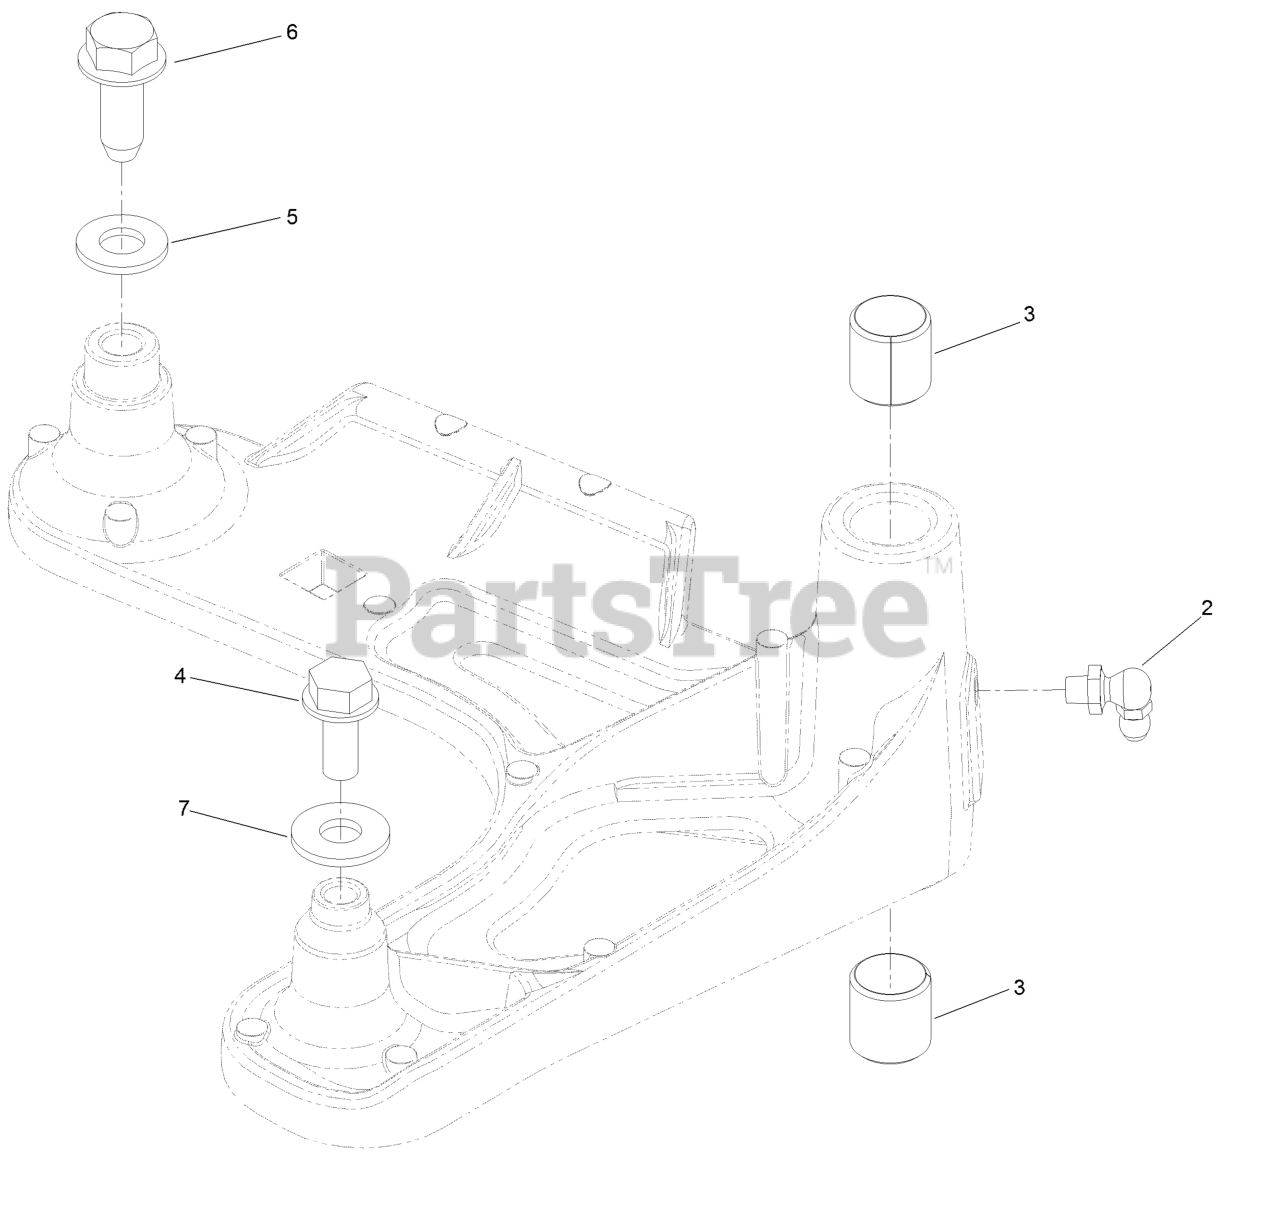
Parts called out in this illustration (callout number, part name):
2	Fitting-Grease, 90 DEG
3	Sleeve-Bearing
4	Screw-HWHTF
5	Washer-Flat
6	Screw-Forming, Thread
7	Washer-Flat
